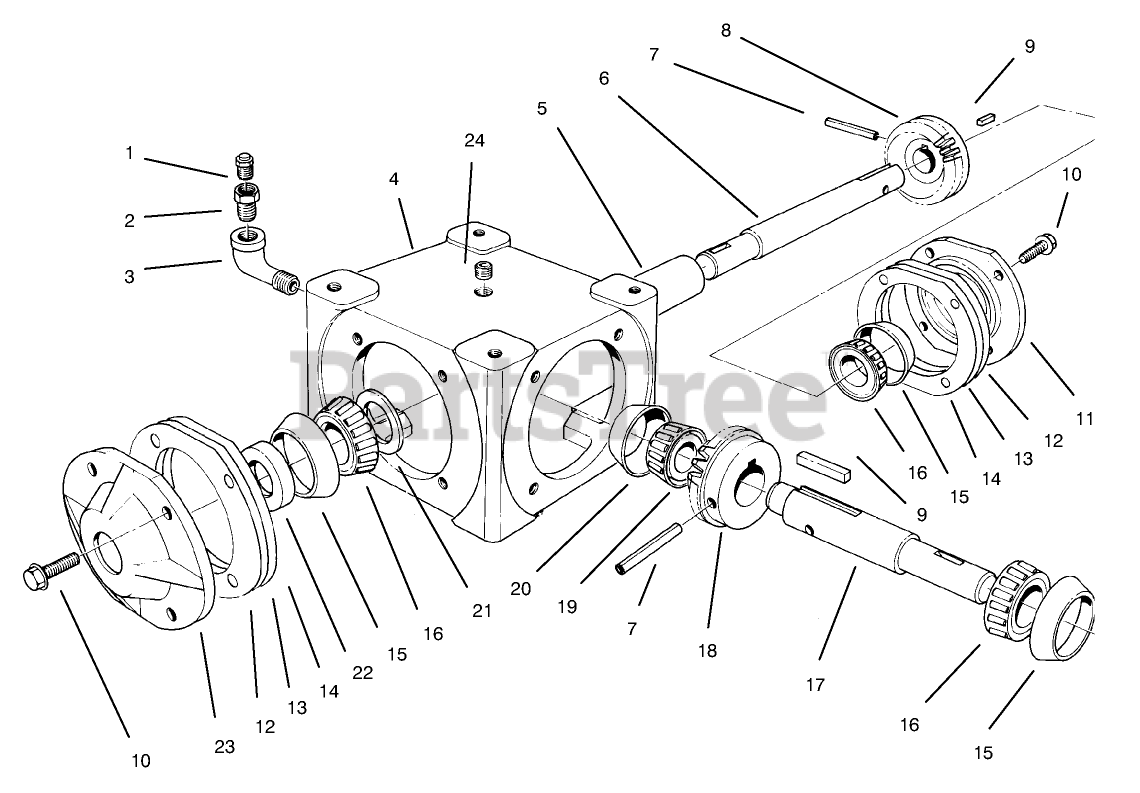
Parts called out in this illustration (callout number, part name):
1	Valve
2	BUSHING
3	Elbow-Street
4	HOUSING
5	SPACER
6	SHAFT
9	Key
10	SCREW-HH (OBS, C/R TO 3234-5)
12	GASKET
13	GASKET
14	GASKET
15	Cup
16	Cone
17	SHAFT
19	Cone
20	Bearing Cup
21	WASHER
22	Seal
24	PLUG (OBS, C/R TO 281-10)
